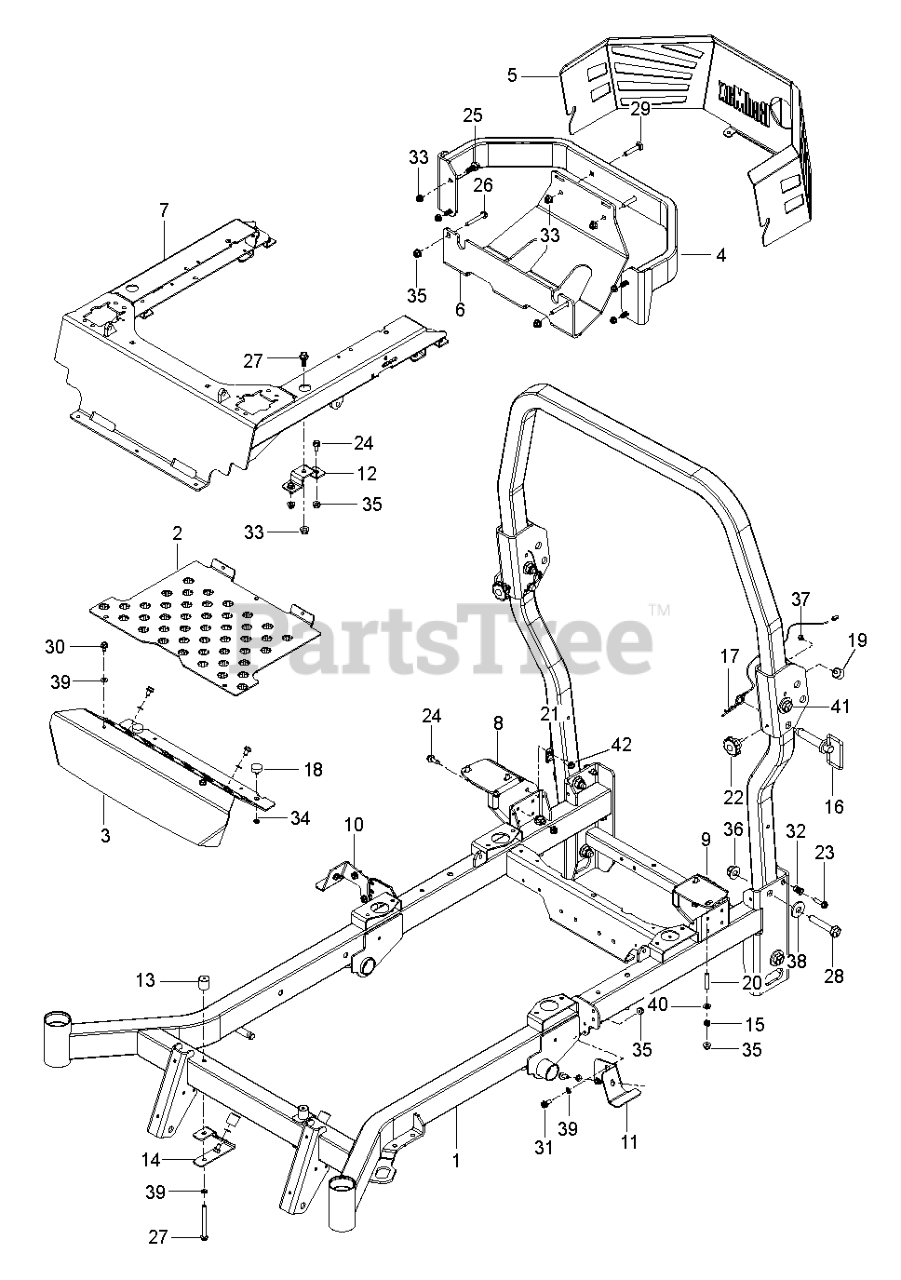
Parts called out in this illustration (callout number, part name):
1	FRAME.W/DECALS/CZT/REDMAX.672
2	PLATE FLOOR PAN SNAPPER RED X6
3	PLATE.FOOT.REST.BLACK
4	BUMPER REAR LONG SNAPPER RED X
5	GUARD REAR SNAPPER RED X672
6	PLATE, SKID, BLACK
7	FRAME SEAT MOUNT SNAPPER RED X
8	MOUNT, RT TANK, BLK
9	MOUNT, LT TANK, BLK
10	BRACKET TANK.FT.RT BLACK MS-43
11	MOUNT, TANK, LT-BLK
12	MOUNT MID-SECTION BLACK MS-431
13	MOUNT, F/F INSERT
14	BRACKET, REST MOUNT
16	PIN.ROPS.W/HANDLE
17	PIN.HAIR.DOUBLE.LOOP.W/LANYARD
18	BUMPER, 1/4-20 STUD, 1/4
19	BUMPER, MALE STUD, 1/4-20
20	STUD, 5/16C
21	DOUBLE TUBE CLAMP
22	KNOB.5/16-18X1"BLACK
23	HHFS 5/16-18 X 1.25 TPBLT GD 5
24	HHFS 5/16-18 X 3/4
25	HHFS 3/8-16 X 1 GRD 5 ZD
26	HHFS 5/16-18 X 2.25 GD 5
27	HHFS 5/16-18 X 3 3/4
28	5/8-11 X 3-1/2 HHB GRADE 5
29	RHSNB 3/8C X 2
30	SCR 5/16-18 X 1/2 SELFTAP ZN
31	SCREW
32	NUTSERT 5/16-18 THICK GRIP
33	NUT 3/8-16 HEX FLG NYLOC ZD
34	JAM NUT 1/4C (2 2 PW01)
35	5/16-18 NYLOC FLANGE NUT
36	NUT 5/8-11 FLG NYLOC ZD
37	RP_NUT 1/4-20 NYLOC
38	WASHER, 5/8 FLAT
39	WASH 5/16 DISC SPRING ZD
40	WASHER
41	BOLT.HEXAG.5/8-11X4-1/4.G5.ZPY
42	HHFS 5/16-18 X 3/4
